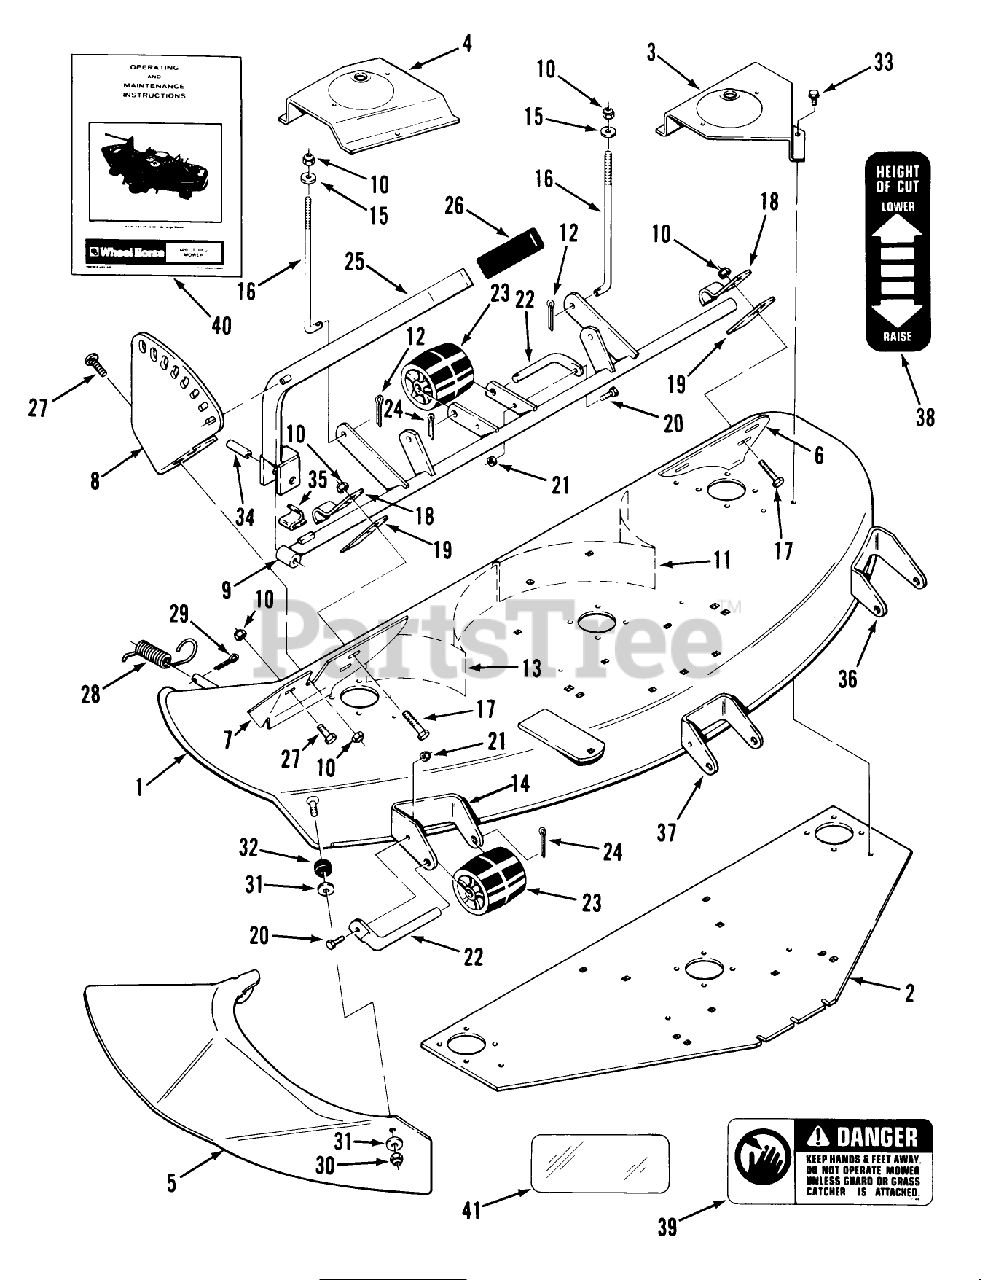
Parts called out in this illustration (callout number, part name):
6	PLATE-WEAR L.H. *R
7	PLATE-WEAR R.H. *R
12	Hairpin
13	BAFFLE-DECK RH
16	ROD-LEVELER
22	ROLLER-SHAFT
32	BUSHING-PIVOT
33	Bolt
34	SPIROL PIN 3/8X1 1/2
35	CLIP-SPRING
36	BRKT-ROLLER
38	DECAL-HOC
40	Operator-s Manual
41	DECAL-OVERLAY
